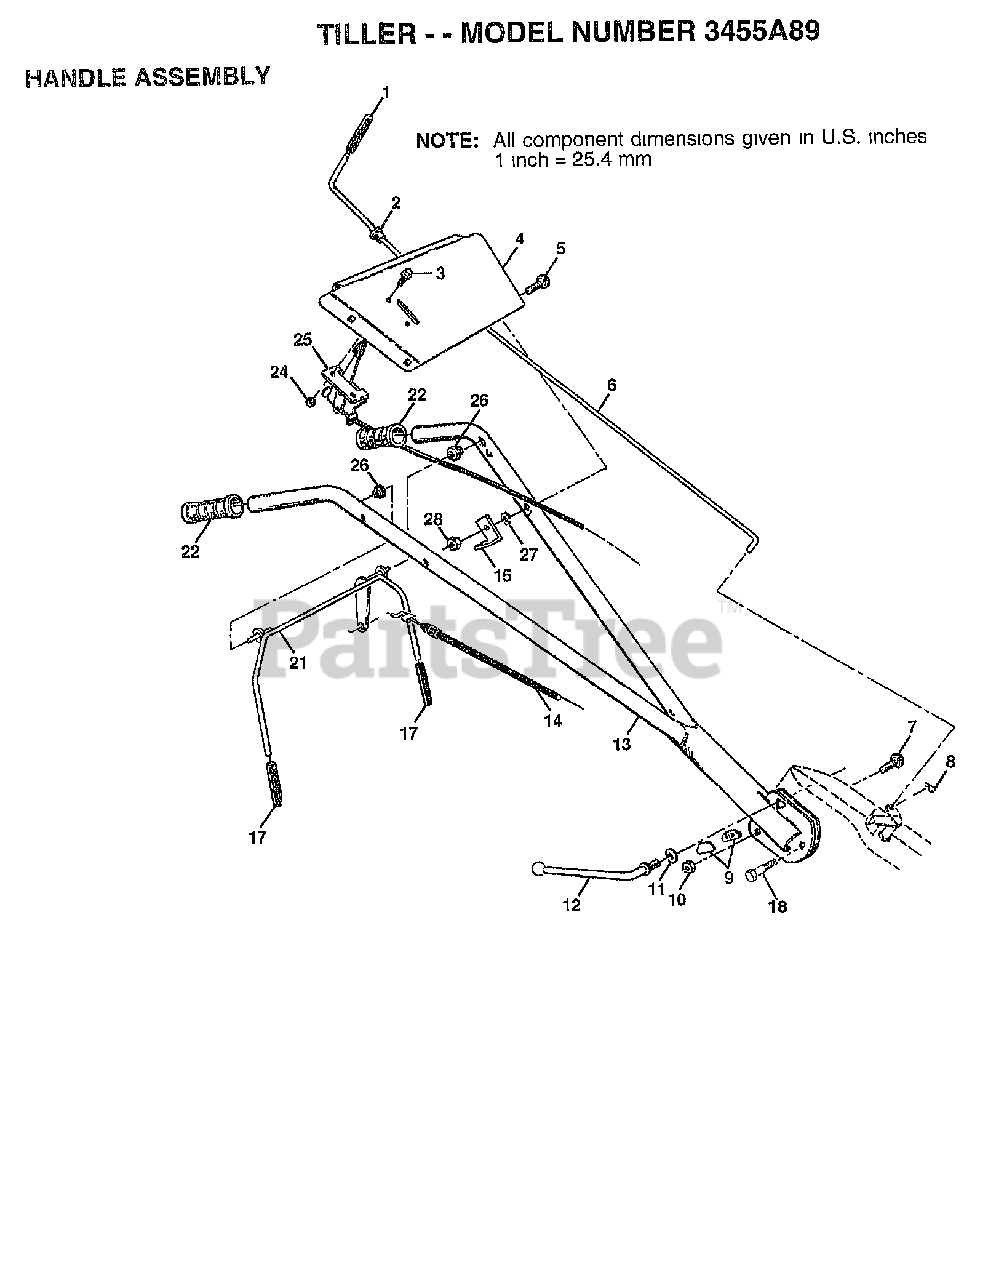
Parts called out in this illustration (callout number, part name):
3	SCREW.PNHD.10-24
4	BRACKET, HANDLE
5	BOLT, CARRIAGE
6	ROD, SHIFT
9	LOCK.HANDLE.CRT
10	LOCKNUT
11	WASHER CRT
12	LEVER.LOCK.CRT
13	HANDLE
14	CABLE, CLUTCH
15	BRACKET, CLUTCH CABLE
17	GRIP BAR CRT(1)
18	BOLT.PIVOT
21	BAR, CONTROL
22	GRIP.1.25.X.4.50
24	NUT **
26	GROMMET, HANDLE
27	LOCKWASHER
28	NUT.71038.31-18.HEX.NYLOCK
